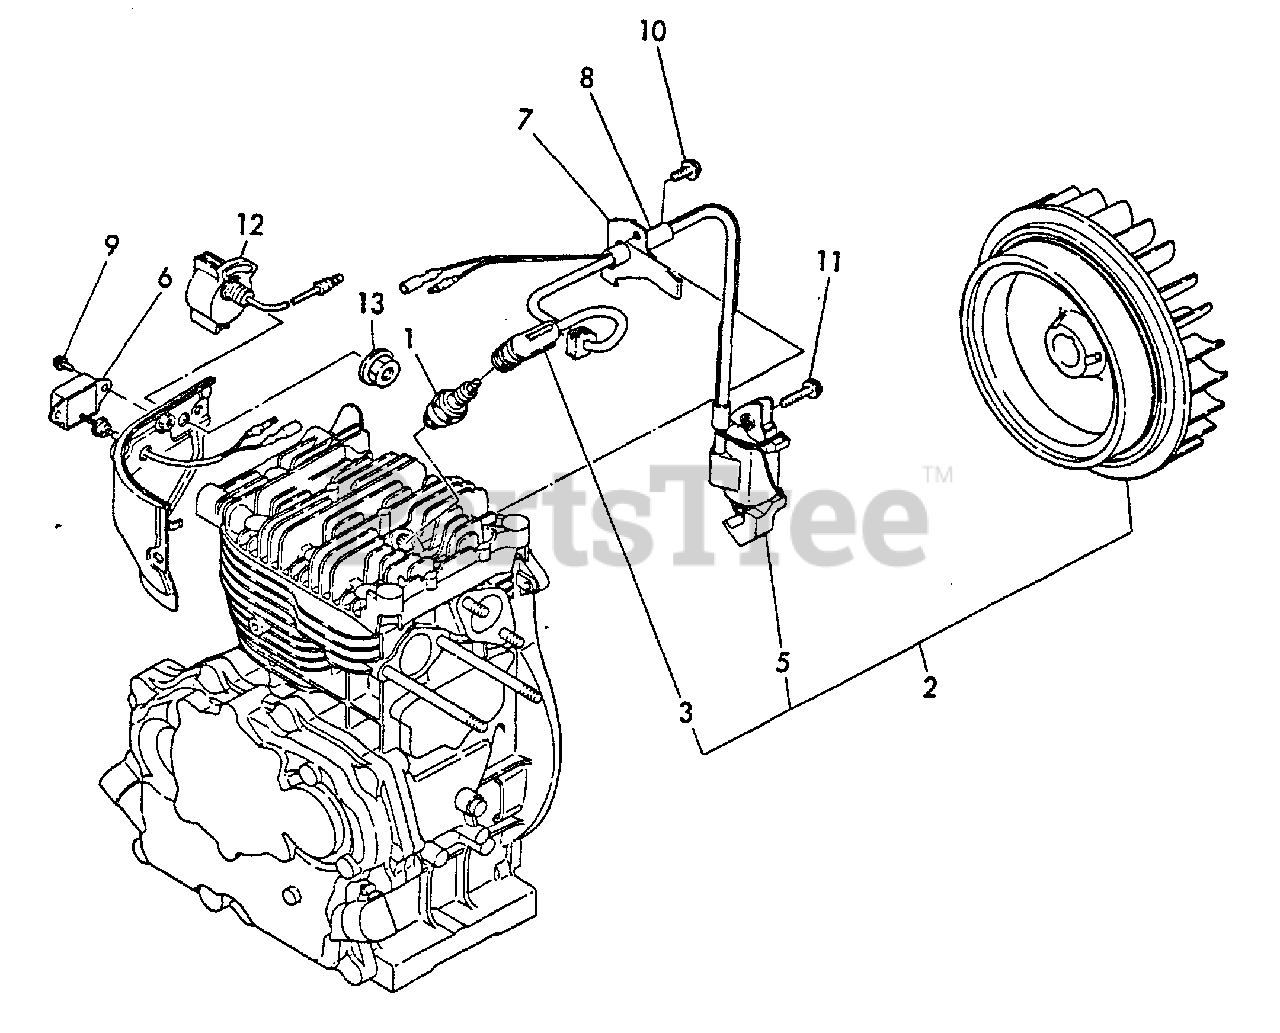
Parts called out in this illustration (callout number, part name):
1	SPARK PLUG
2	FLYWHEEL MAGNETO ASSY
3	CAP, PLUG
5	COIL, IGNITION
6	IGNITER
7	CLAMP
8	TUBE, INSULATOR
9	SCREW - 5X10
10	BOLT - 6X8 -- PLATED
11	BOLT - 6X25
12	IGNITION SWITCH ASSY
13	NUT - 8
